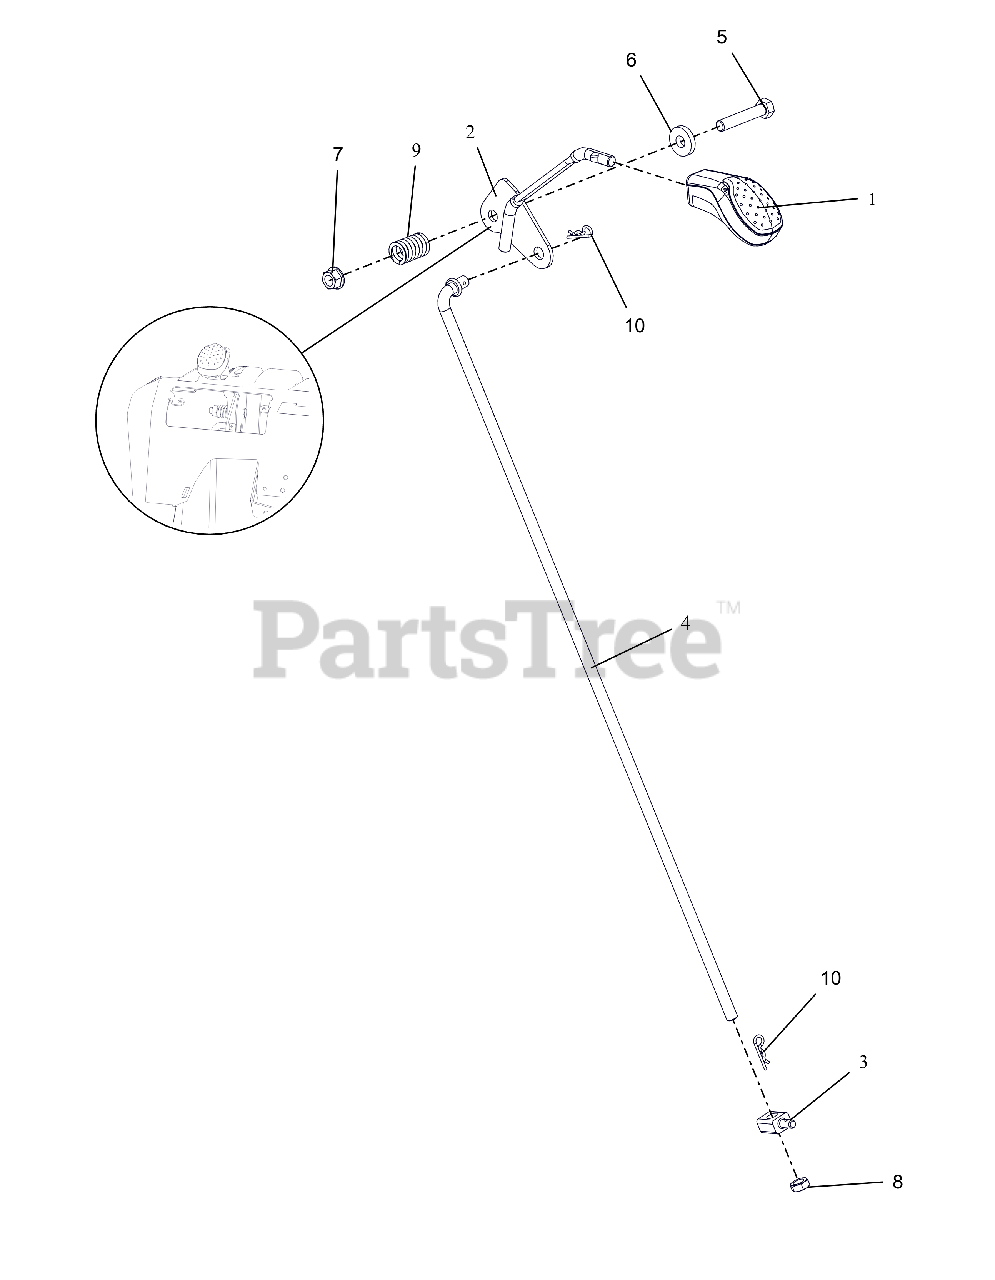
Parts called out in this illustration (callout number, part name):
1	KNOB, CONTROL, DASH
2	WELDMENT,LG DASH SPEED CONTROL
3	PIVOT,SHIFT ROD .375-16(TRUNN)
4	ROD, SHIFT-PRO
5	BLT,HEX .38-16X2.00 G5 ZCC
6	WSHR, FLT .406X1.00X.188 ZCC
7	NUT-LK-TOP-FLG .38-16 ZC120
8	NUT-JAM .375-16 G2 ZCC
9	SG-COMP .125X.781X1.250
10	PIN, HAIR #213 .08X1.19 ZCC
